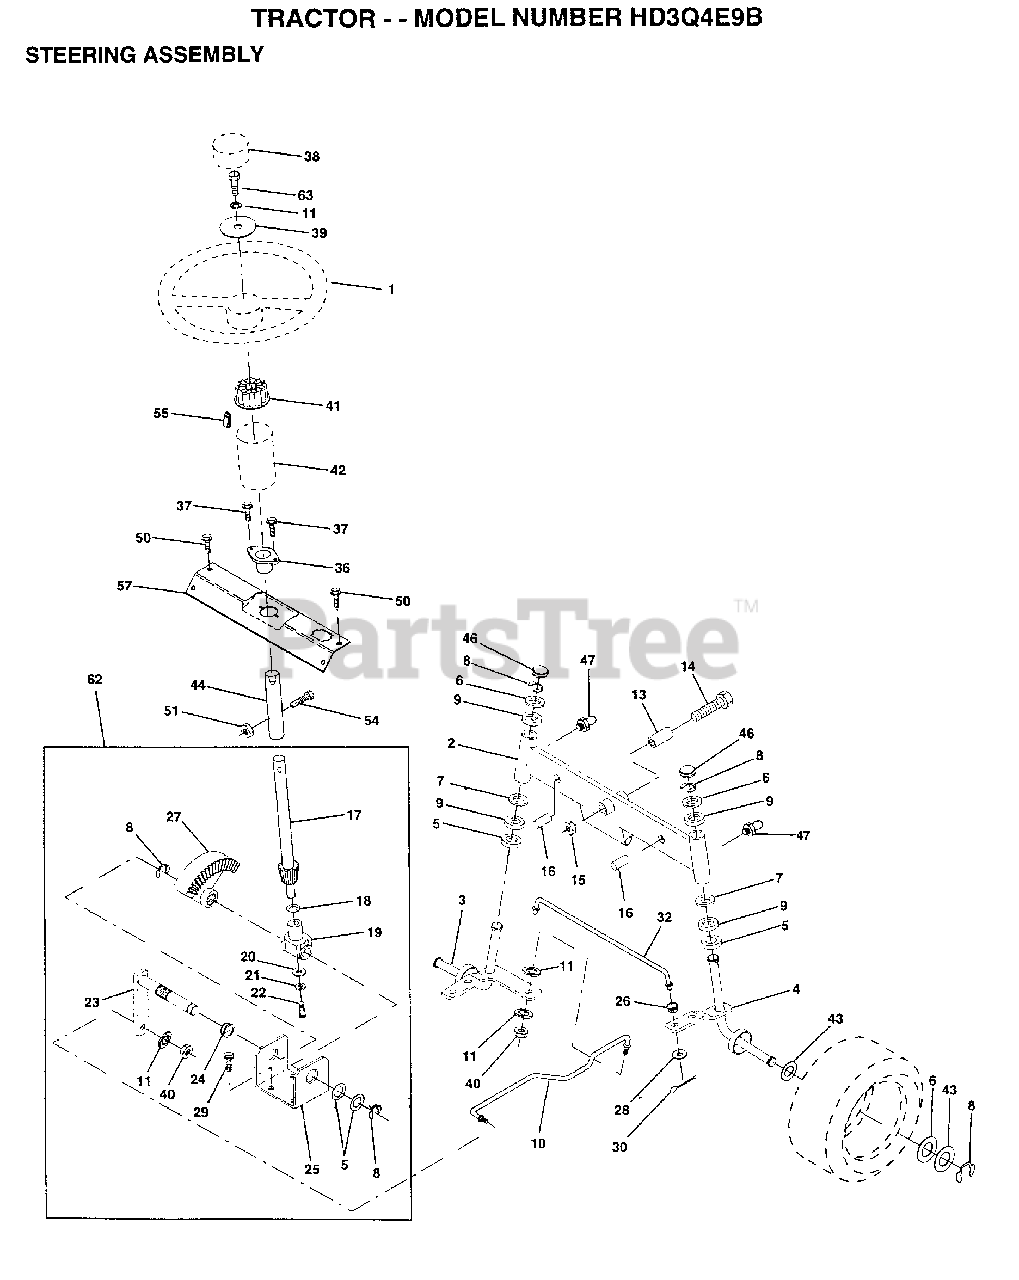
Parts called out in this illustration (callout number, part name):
1	WHEEL STR AYP BLK
2	AXLE ASM FRONT
3	SPINDLE LH
4	SPINDLE RH
5	WASHER .T
6	WASHER
7	WASHER
9	COL. SRTG. BEAR.
11	LOCKWASHER
13	BEARING
14	BOLT HEX 5/8-11
15	"NUT-LOC,FLANGE LT"
16	AXLE PIN
17	SHAFT ASM STEERIN
18	THRUST WASHER
19	SUPPORT.SHAFT
21	LOCKWASHER
22	SCREW.SCKTHD.CAP
24	NYLINER T
25	"BRKT,STEERING"
26	BUSHING.DRAGLINK
27	GEAR SECTOR
28	WASHER
29	SCREW
30	COTTER PIN
32	TIE ROD
37	"SCREW-TT,10-32 FL"
38	CAP STEER AYP
39	WASHER T
40	GRIPCO NUT
41	ADAPTER LT
42	BOOT SHAFT STEER
43	WASHER
44	SHAFT EXT STEERIN
46	CAP
47	ZERK M
50	SCREW HEX CRT
51	NUT
54	BOLT
55	CLIP TINNERMAN
57	SUPPORT SHAFT STR
63	BOLT
